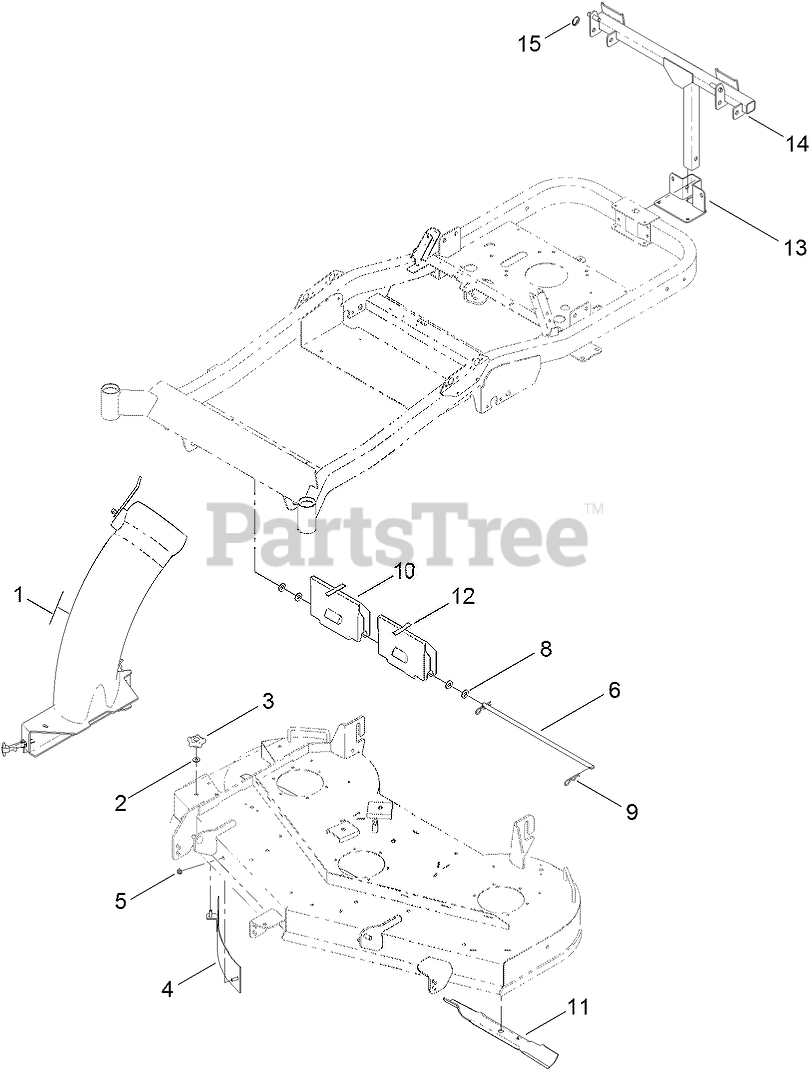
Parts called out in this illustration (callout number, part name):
1	CHUTE ASM
2	WASHER-FLAT
3	KNOB-LOCKING
4	BAFFLE-BAGGER
5	NUT-HF, NI
6	ROD-DECK, PIVOT
8	WASHER-FLAT
9	PIN-HAIR
10	WEIGHT-BAGGER
11	BLADE-HI LIFT, 18.75 INCH
12	BUMPER-PAD
13	SUPPORT-BAGGER
14	FRAME-PIVOT
15	PIN-COTTER, CIRCULAR
